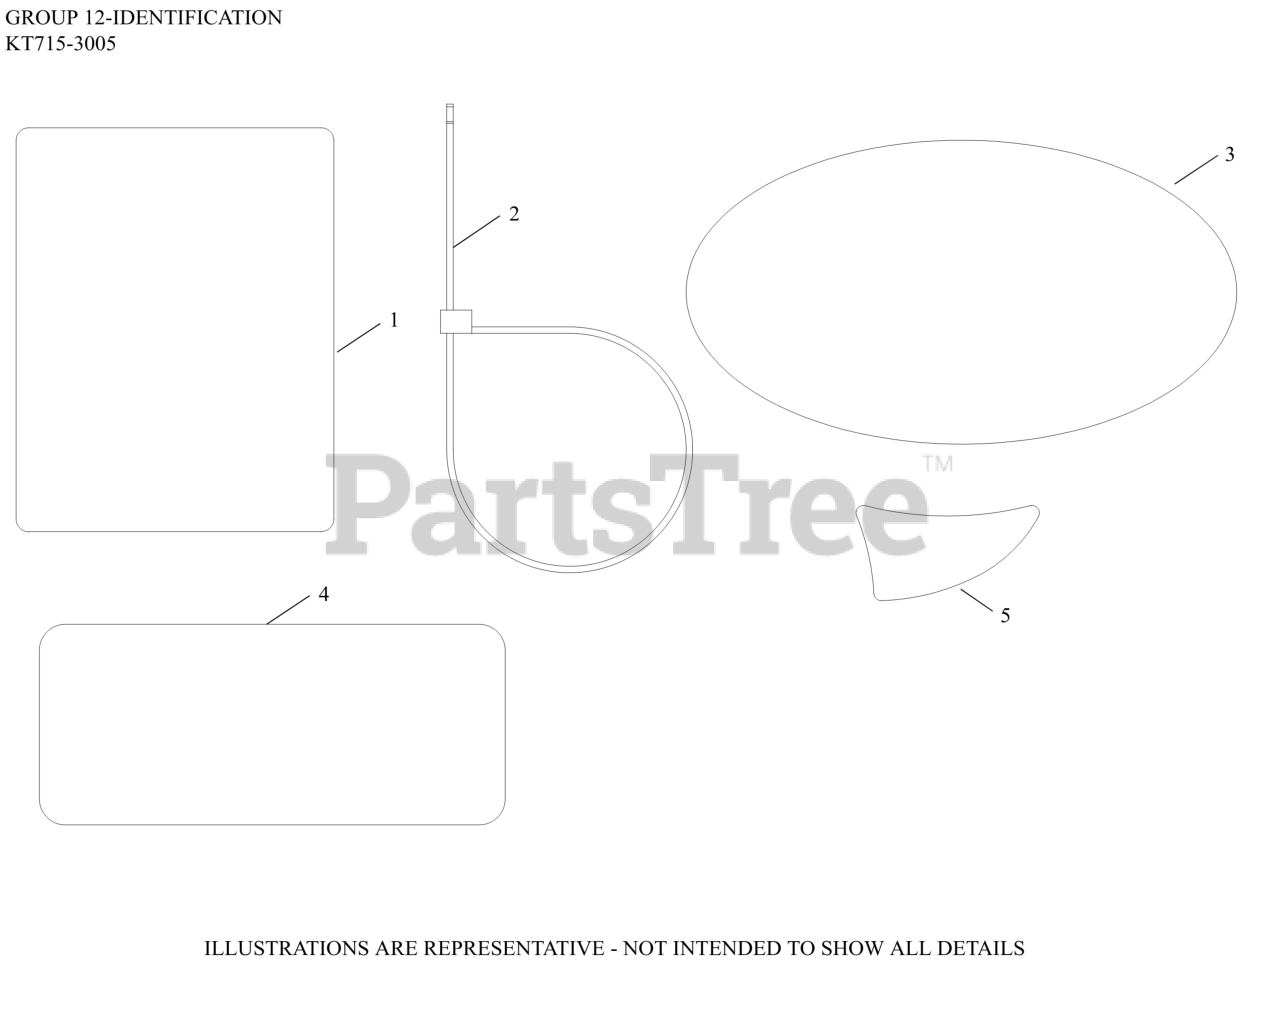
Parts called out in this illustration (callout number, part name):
1	LABEL, CLEAR LAMINATION
3	LABEL, 7000 SERIES (20HP, PRO)
4	LABEL, CANADIAN COMPLIANCE
5	LABEL, SMART CHOKE
